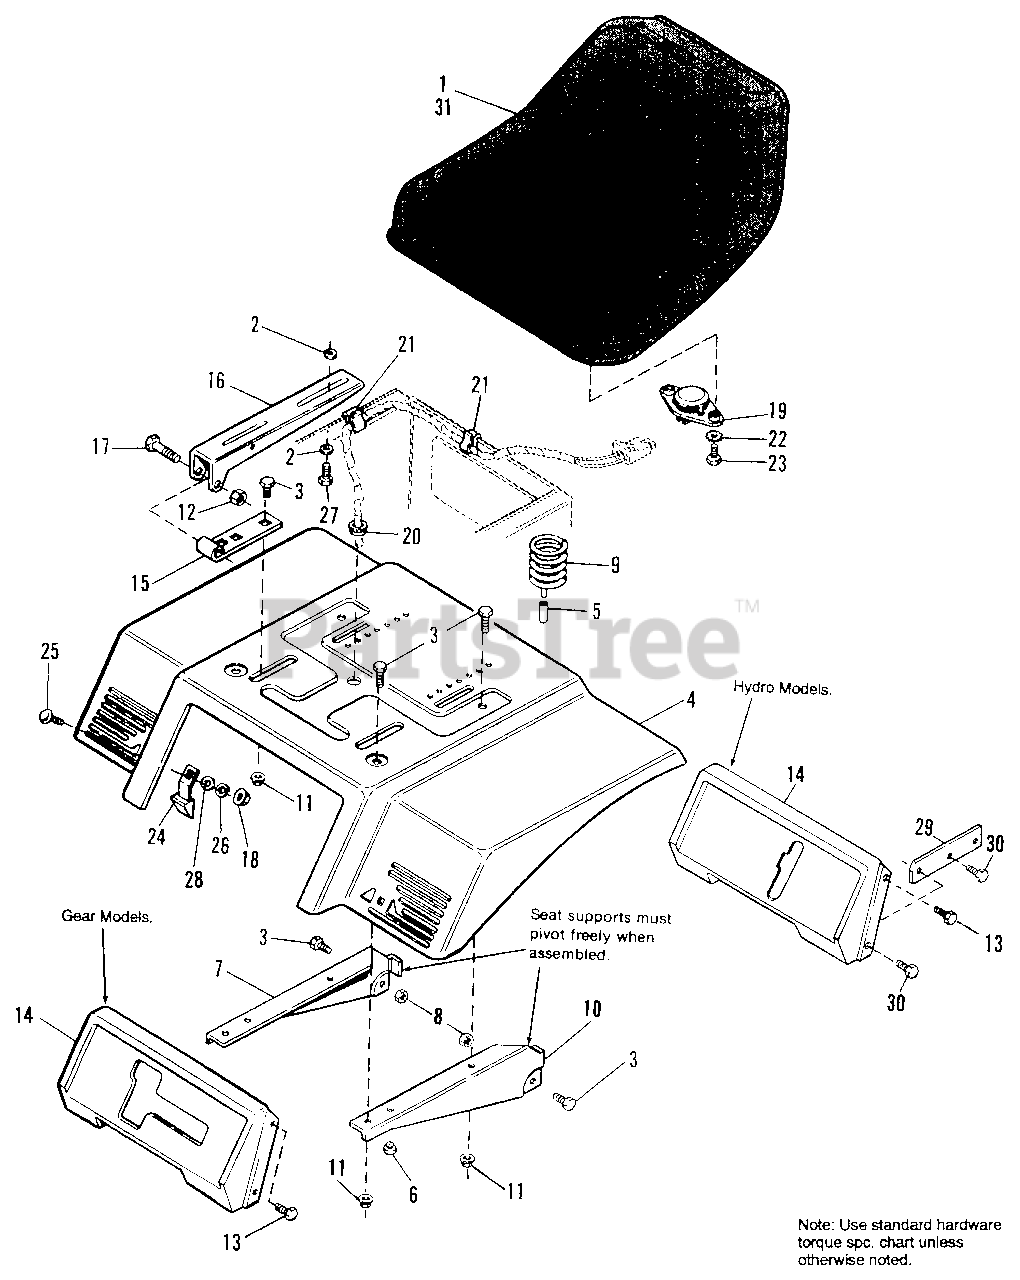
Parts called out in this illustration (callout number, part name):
1	SEAT (Incl. Ref. No. 31)
2	WASHER, Plain, 5/16
3	CAPSCREW, Hex, 5/16-18 x 3/4
4	DECK, Seat
5	COVER, Wire
6	BUMPER, Plug
7	SUPPORT, Seat, R.H.
8	LOCKNUT, Hex, 5/16-18
9	SPRING, Seat
10	SUPPORT, Seat, L.H.
11	NUT, Hex, Flange, Whizlock, 5/16-18
12	LOCKNUT, Hex, 3/8-16
13	SCREW, Hex, Taptiite, 5/16-18 x 3/8 (Gear models, Mfg. Nos. 1692160, 1692166)
14	PANEL, Shift (Gear models, 1692160, 1692166)
14	PANEL, Shift Hydro models, Mfg. Nos. 1692156, 1692164)
15	HINGE, Lower
16	HINGE, Upper
17	CAPSCREW, Hex, 3/8-6 x 2
18	NUT, Hex, Full, 5/16-18
19	SWITCH, Seat
20	BUSHING, Snap
22	LOCKWASHER, 1/4 Ext. Tooth
23	SCREW, Rd. Hd., 1/4-20 x 3/4
24	SEAT LATCH ASSY.
25	CARRIAGE BOLT, 5/16-18 x 3/4
26	LOCKWASHER, 5/16
27	CAPSCREW, Hex Hd., 5/16-18
28	WASHER, 5/16 Std.
29	BRACE, Shift (Hydro models, Mfg. Nos. 1692156, 1692164)
30	SCREW, Taptite, 1/4-20 x 3/8 (Hydro models, Mfg. Nos. 1692156, 1692164, 1692259, 16922630)
31	SEAT COVER
